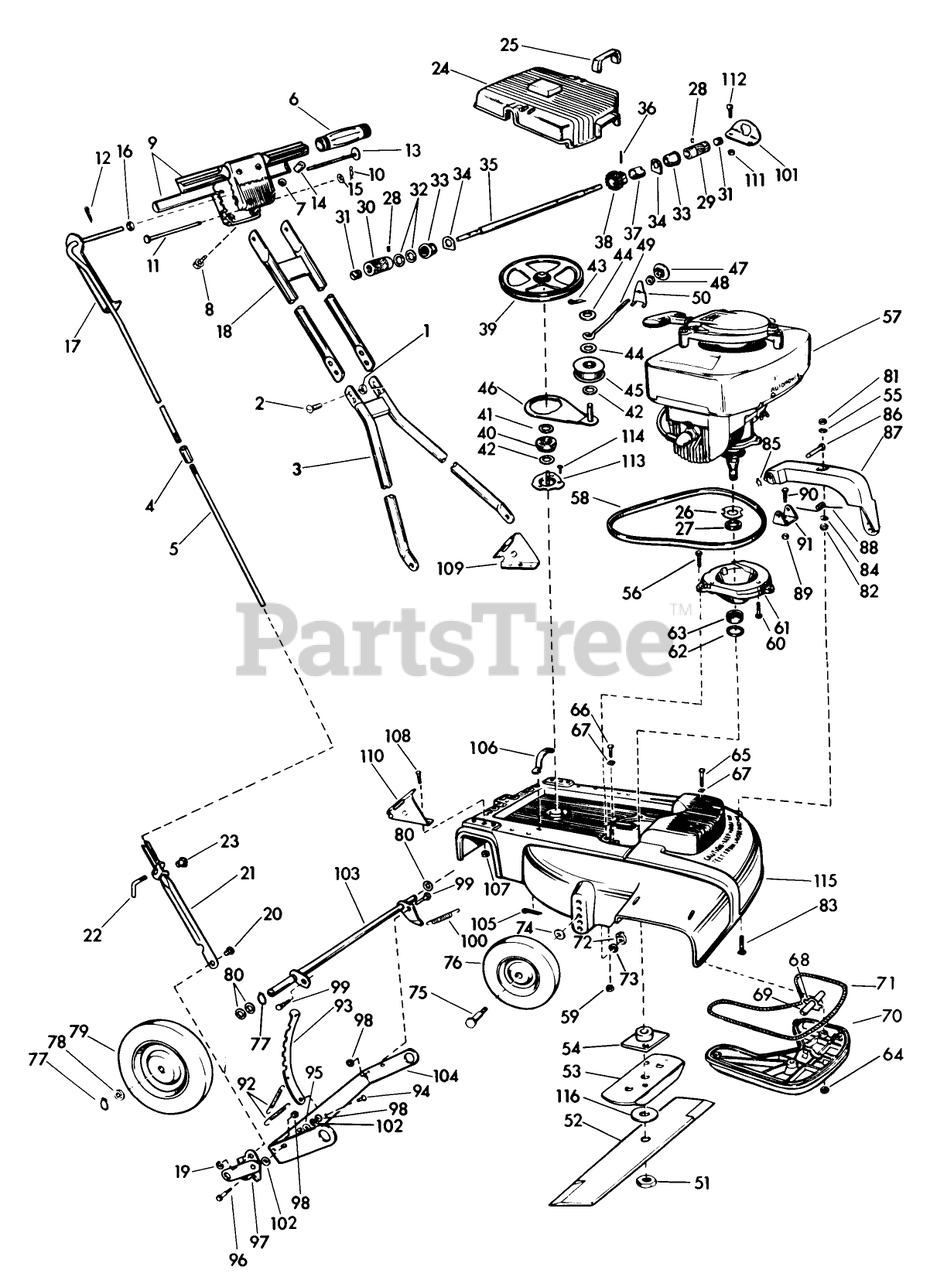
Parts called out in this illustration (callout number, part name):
1	STOP NUT
12	Pin-Cotter
16	Washer-Control Rod
24	Cover-Pulley, 18"
24	Cover-Pulley, 21"
31	GREASE PLUG
35	Drive Shaft, 18"
40	Felt-Oiler (Cup)
47	Knob-Speed Change
49	Rod-Speed Change
50	Lock-Speed Change
51	NUT-BLADE
52	Blade-21"
54	PLATE AND COLLAR ASM
55	Washer-Level Ride, Fiber
58	Belt-V, 29" Class 3L, Fractional H.P. 18" Model
64	LOCKNUT E
66	Bolt-Muffler
67	Gasket-Muffler Bolt
68	Gasket-Internal Tube
69	Tube-Internal Muffler
70	Muffler
73	WASHER, LOCK
77	RETAINING RING
81	STOP NUT
82	Jam Nut
83	Bolt-Level-Ride Arm
84	Washer-Level Ride Arm
85	Hair Pin-Level Ride Arm
86	Pin-Level Ride Arm
87	Arm-Level Ride
88	Spring-Level Ride Arm
89	STOP NUT
90	Screw-Level-RideArm Bracket
91	Bracket-Level Ride Arm
93	Lever-Height Adjustment
96	BOLT RB&W
98	STOP NUT
99	BOLT RB&W
102	WASHER S
104	Bracket-Axle, 18"
111	STOP NUT
